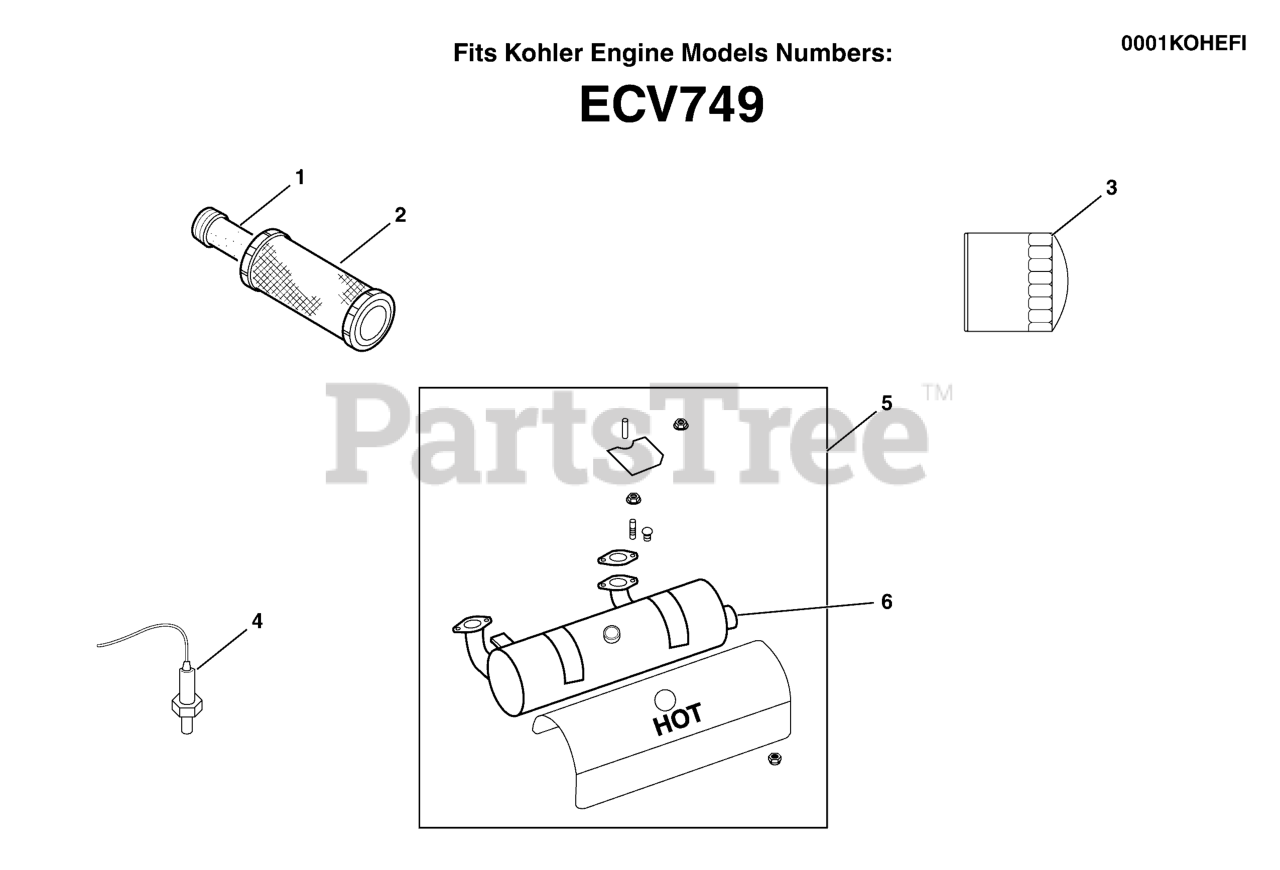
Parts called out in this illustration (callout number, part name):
1	ELEMENT ASSEMBLY, INTERNAL
2	ELEMENT ASSY
3	OIL FILTER, KOH, EFI, 25 050 44
4	OXYGEN SENSOR, KOHLER
5	MUFFLER KIT, KOHLER (ALSO AVAILABLE THROUGH KOHLER. KOHLER P/N: 24 786 29-S)
6	MUFFLER, KOHLER, OIL FILTER SIDE
